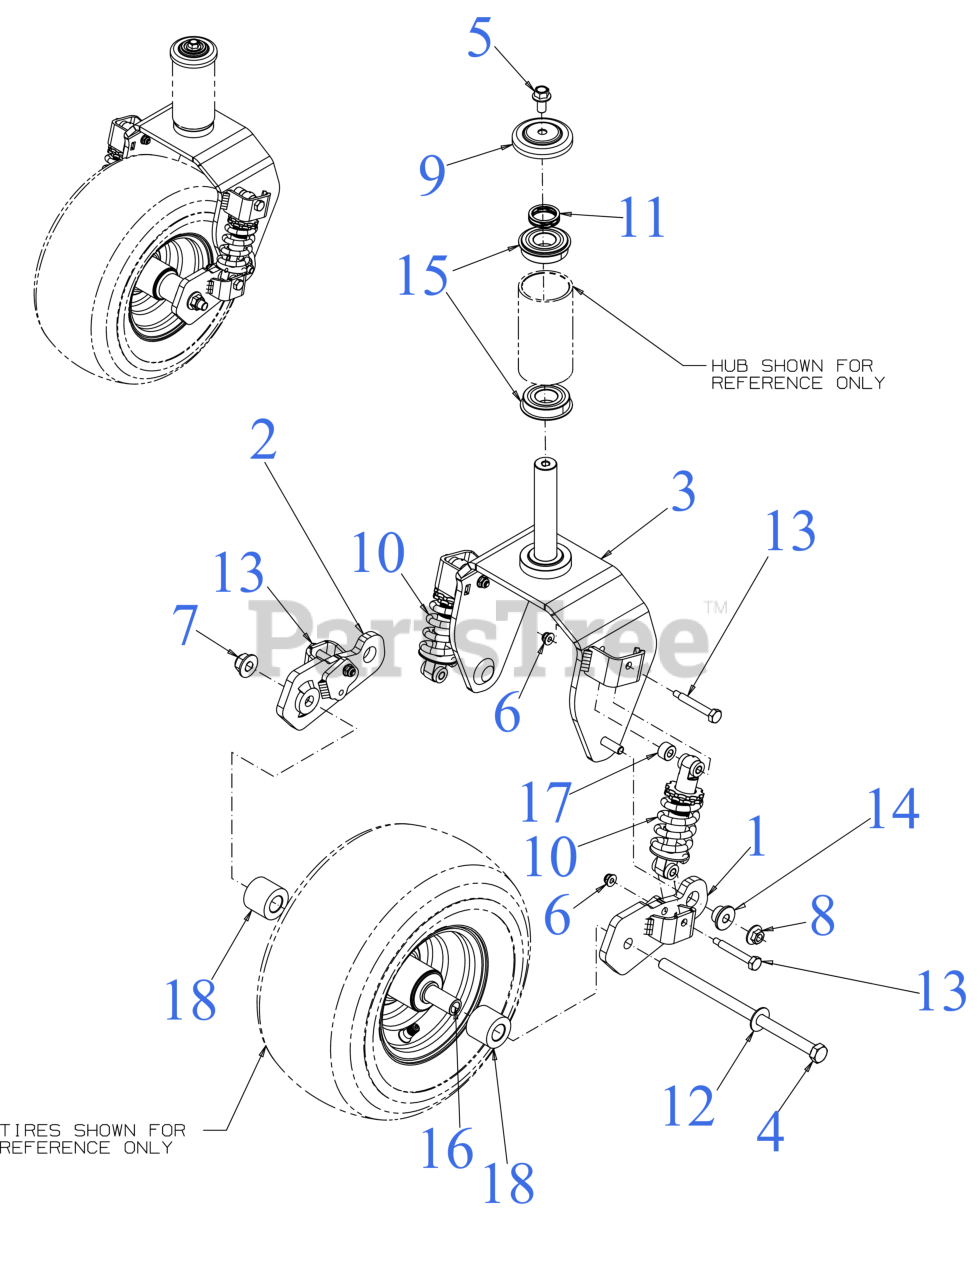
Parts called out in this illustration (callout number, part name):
1	CASTER PIVOT BRACKET (RH)
2	CASTER PIVOT BRACKET (LH)
3	CASTER WHEEL YOKE
4	SCREW 1/2-13 x 9.5 GR5
5	BOLT - 3/8-16:.75:GR5:PATCH LOCK
6	FLANGE LOCK NUT
8	FLANGE LOCK NUT
10	SHOCK ABSORBER
11	WAVE WASHER
12	FLAT WASHER
13	SHOULDER SCREW
14	SHOULDER SPACER
15	BALL BEARING 25X52X15
16	CASTER AXLE SPACER
17	SPACER .330X.715X.430
18	CASTER WHEEL SPACER
